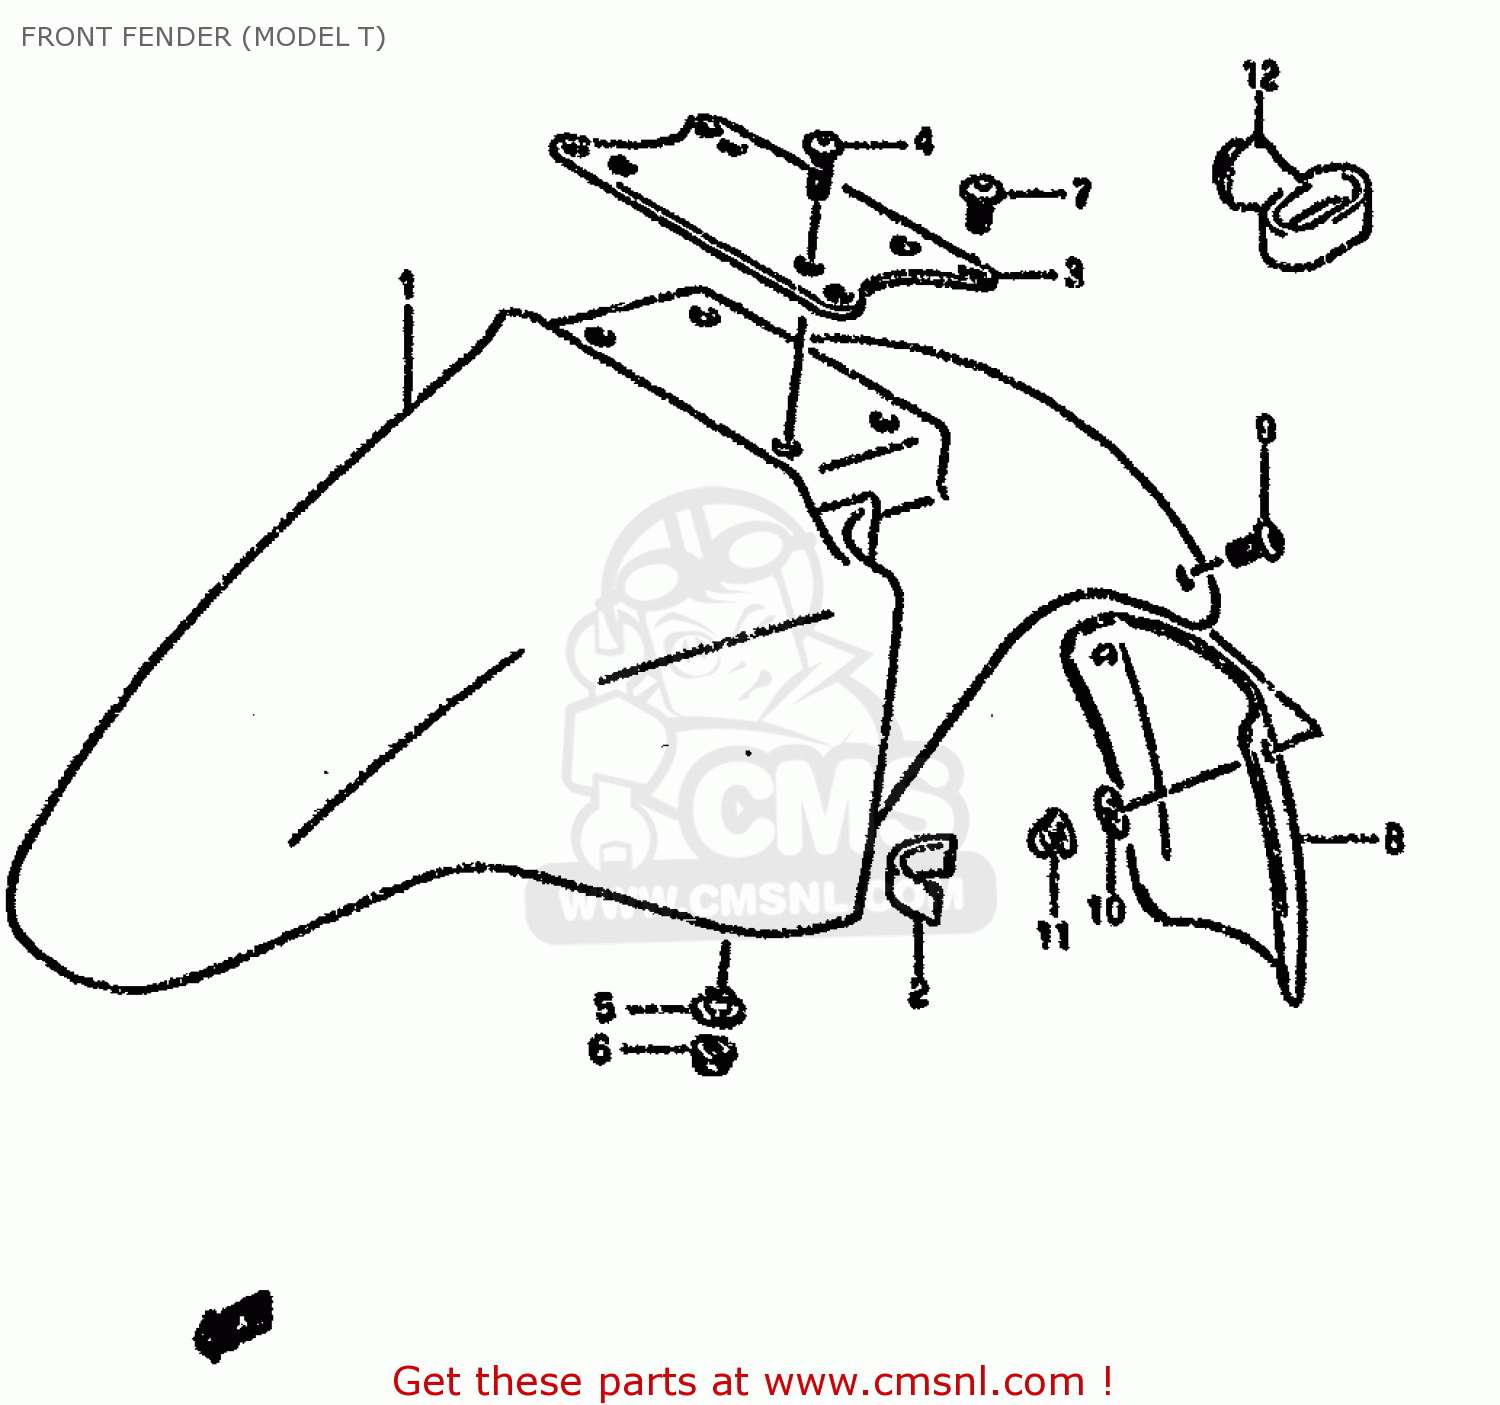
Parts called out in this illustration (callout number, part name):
1	FENDER,FRONT
2	CUSHION,FR FENDER
3	BRACE,FR FENDER
4	SCREW(5X16)
5	WASHER
6	NUT
7	SCREW(6X12)
8	MUDGUARD,FR FENDER
9	SCREW
10	WASHER(5.5X20X1.2)
11	NUT
12	GUIDE,CABLE
